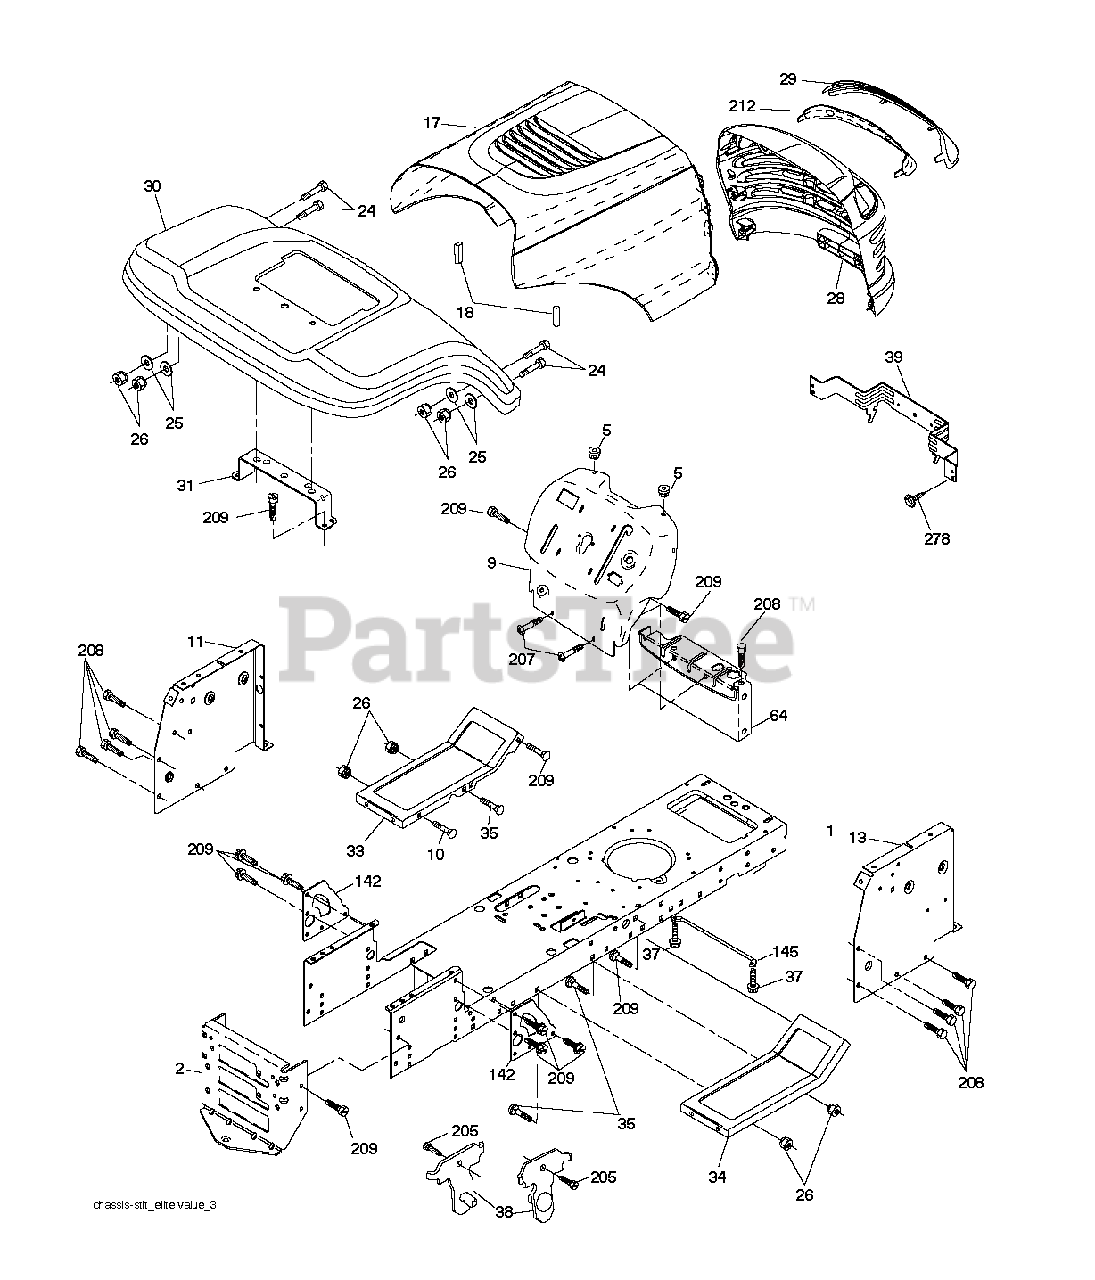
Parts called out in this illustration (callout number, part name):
1	CHASSIS STAMPING
2	DRAWBAR, 12GA
5	BUMPER.RUBBER.HOOD
10	BOLT D
11	PANEL.DASH.LH.LTX
18	BUMPER.HOOD.LARGE.1.75"
25	WASHER
26	NUT
31	BRACKET FENDER
38	BRACKET.ASM.PIVOT.MOWER.REAR
39	BRACKET PIVOT
64	DASH LOWER
142	PLATE REINFORCEMENT
145	ROD.PIVOT.HOOD
207	SCREW, 5/16-18 X 1/2
208	SCREW 3/8-16X1/2
209	SCREW, 3/8-16X3/4
278	SCREW.#10 X 0.750.BOS THREAD
